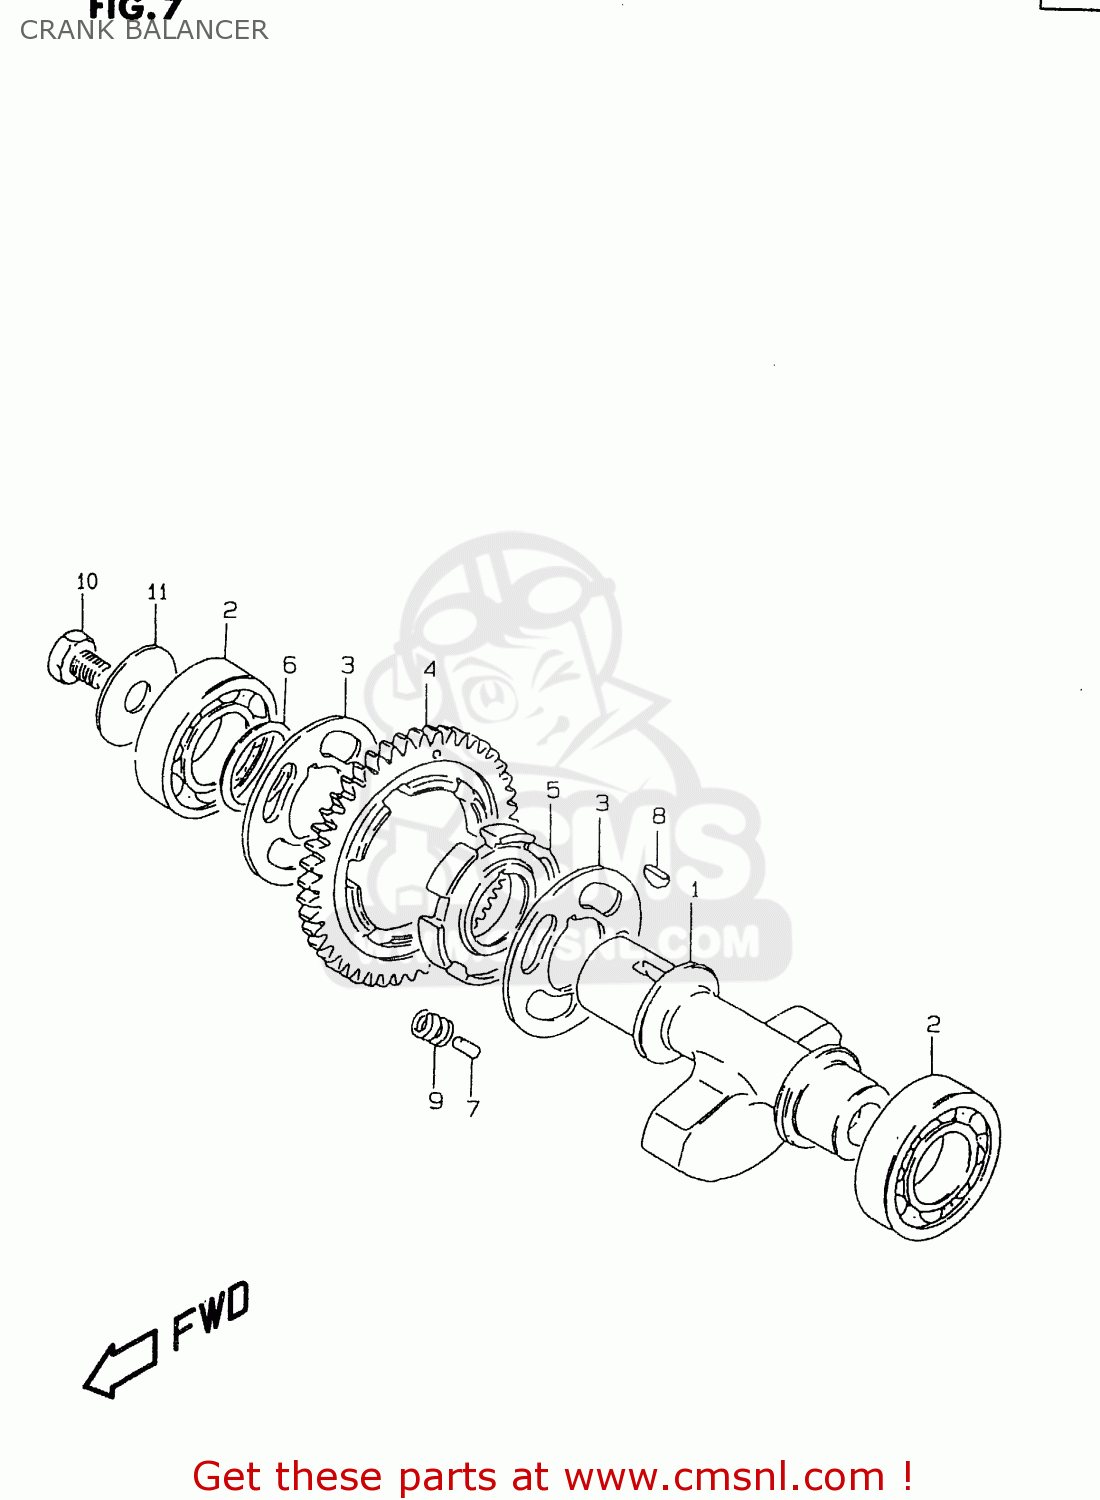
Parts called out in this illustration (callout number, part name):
1	SHAFT,CRANK BALANCER
2	BEARING(25X62X17)
3	WASHER
4	GEAR,CRANK BAL DRIVEN(NT:46)
5	RACE,CRK BAL DRIVEN GR INNER
6	SHIM(25X36X0.5)
7	PIN(4.5X9.5)
8	KEY
9	SPRING
10	Bolt
11	WASHER(12X40X2.5)
